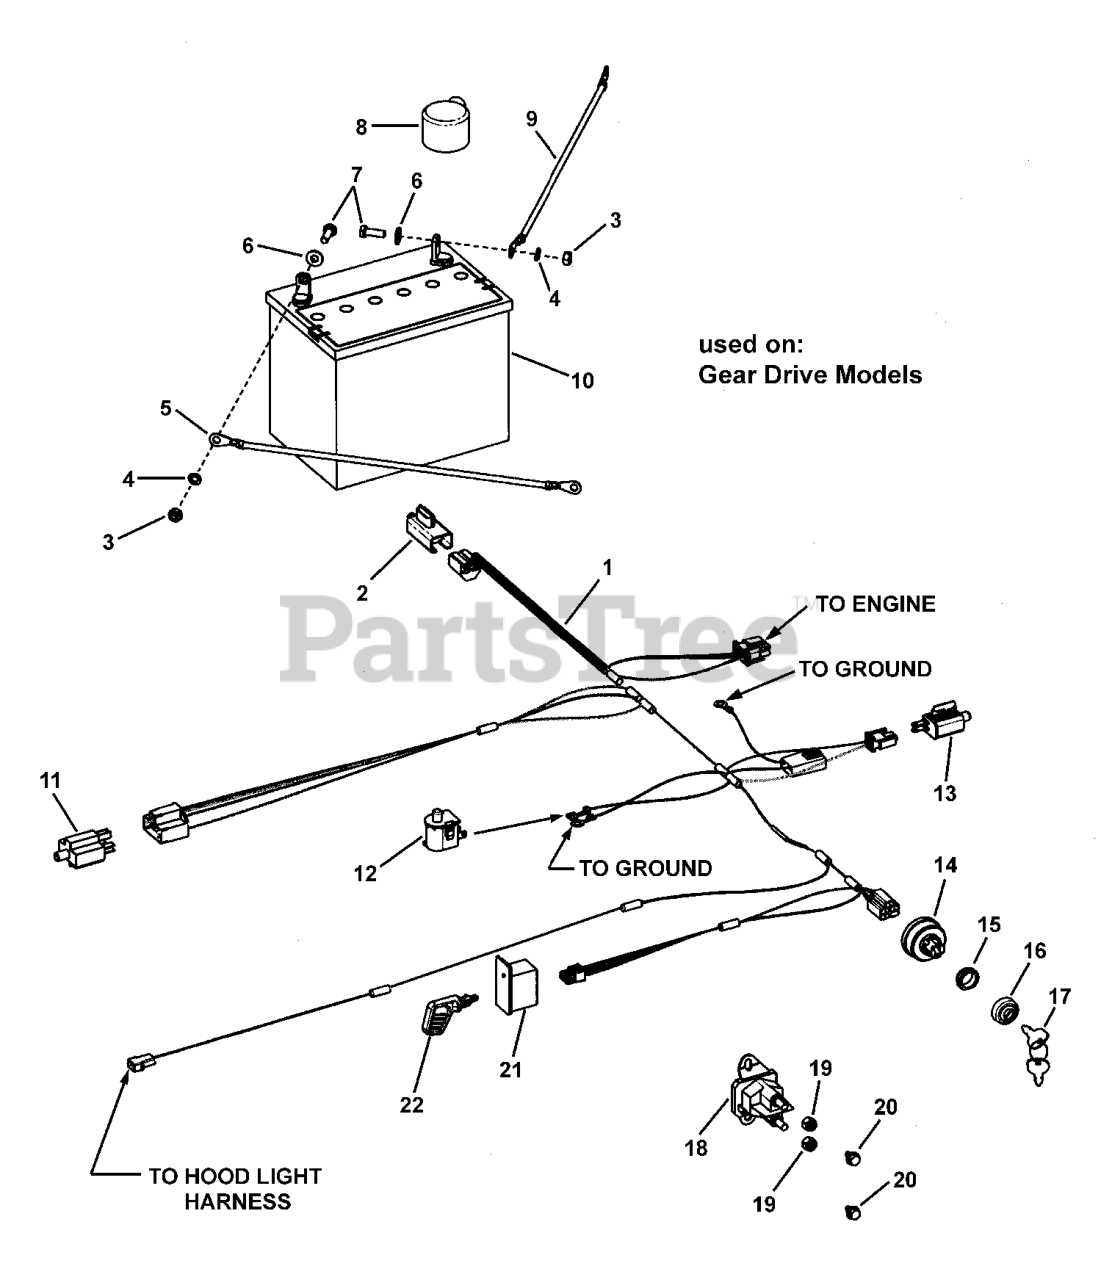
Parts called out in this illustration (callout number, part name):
1	HARNESS, WIRING, GEAR, TCT, MY'08
2	SWITCH, LIMIT, NO/NC, SNAP-IN
3	NUT-HEX 1/4-20 NC-2B YELLOW
4	LOCKWASHER, 1/4
5	CABLE-BAT 8GA 12.00L - BLACK
6	WASHER, 0.250(0.27IDX0.62ODX.05THK)YEL
7	CAPSCREW, HEX HD 1/4-20X0.750 G5 YEL
8	BOOT BATTERY POSITIVE
9	CABLE-BAT 8GA 18.00L - RED
10	BATTERY KIT, 12 VOLT, 230 CCA
11	SWITCH, 3 POLE, PLUNGER, SNAP-IN
12	SWITCH, Seat, Push Button (NC)
13	SWITCH, LIMIT, NO, SNAP-IN
14	SWITCH, IGNITION-AFTERFIRE SOLENOID
15	NUT, 5/8"-32 E-START
16	CAP, E-START
17	KEY IGNITION INDAK (SET OF 2)
18	SOLENOID - 3 POLE
19	NUT, HEX LOCK 1/4-20 BZ
20	SCREW, 1/4-14X.38"ST
21	SWITCH, RMO Module Only
22	KEY, RMO Module Plastic
